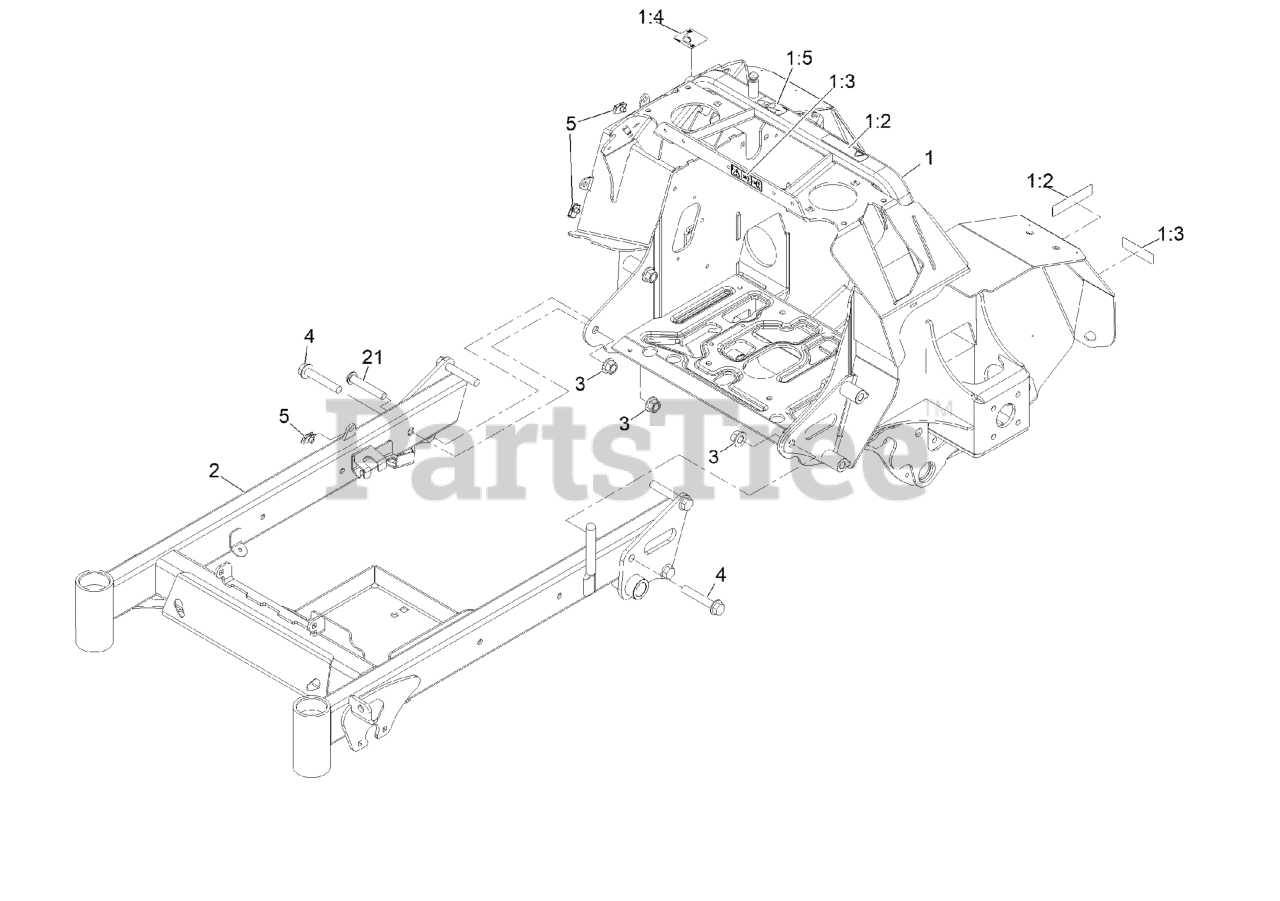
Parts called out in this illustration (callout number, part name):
1	ASM, REAR FRAME W/ DECALS
1:2	DECAL-WARNING
1:3	DECAL, COVER MISSING
1:4	DECAL-PARK BRAKE, CE
1:5	DECAL-BELT ROUTING HYD
2	WELD, FRONT FRAME, 36
3	Nut-Lock 1/2-13
4	SCREW-HF
21	SCREW, HSBH
